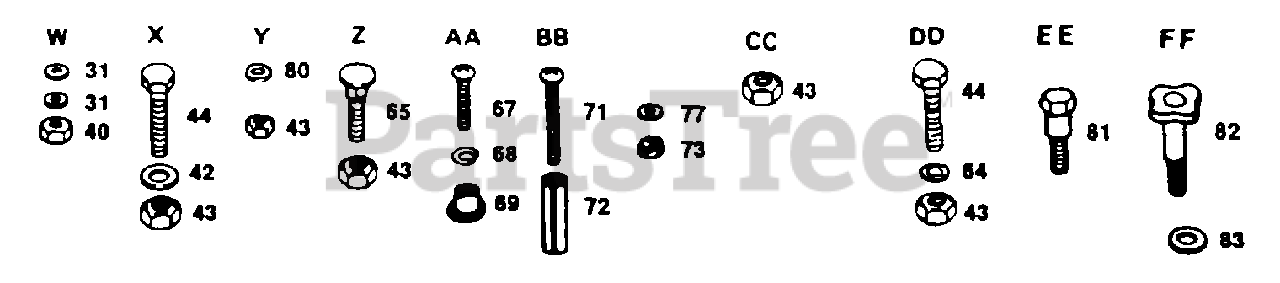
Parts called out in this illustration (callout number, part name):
31	WASHER PM
42	WASHER
44	BOLT
64	WASHER
65	BOLT
67	SCREW
68	LOCKWASHER
69	WELDNUT
71	SCREW
72	SPACER LT
77	WASHER
80	WASHER
82	"KNOB 1/2"" YT"
83	WASHER
